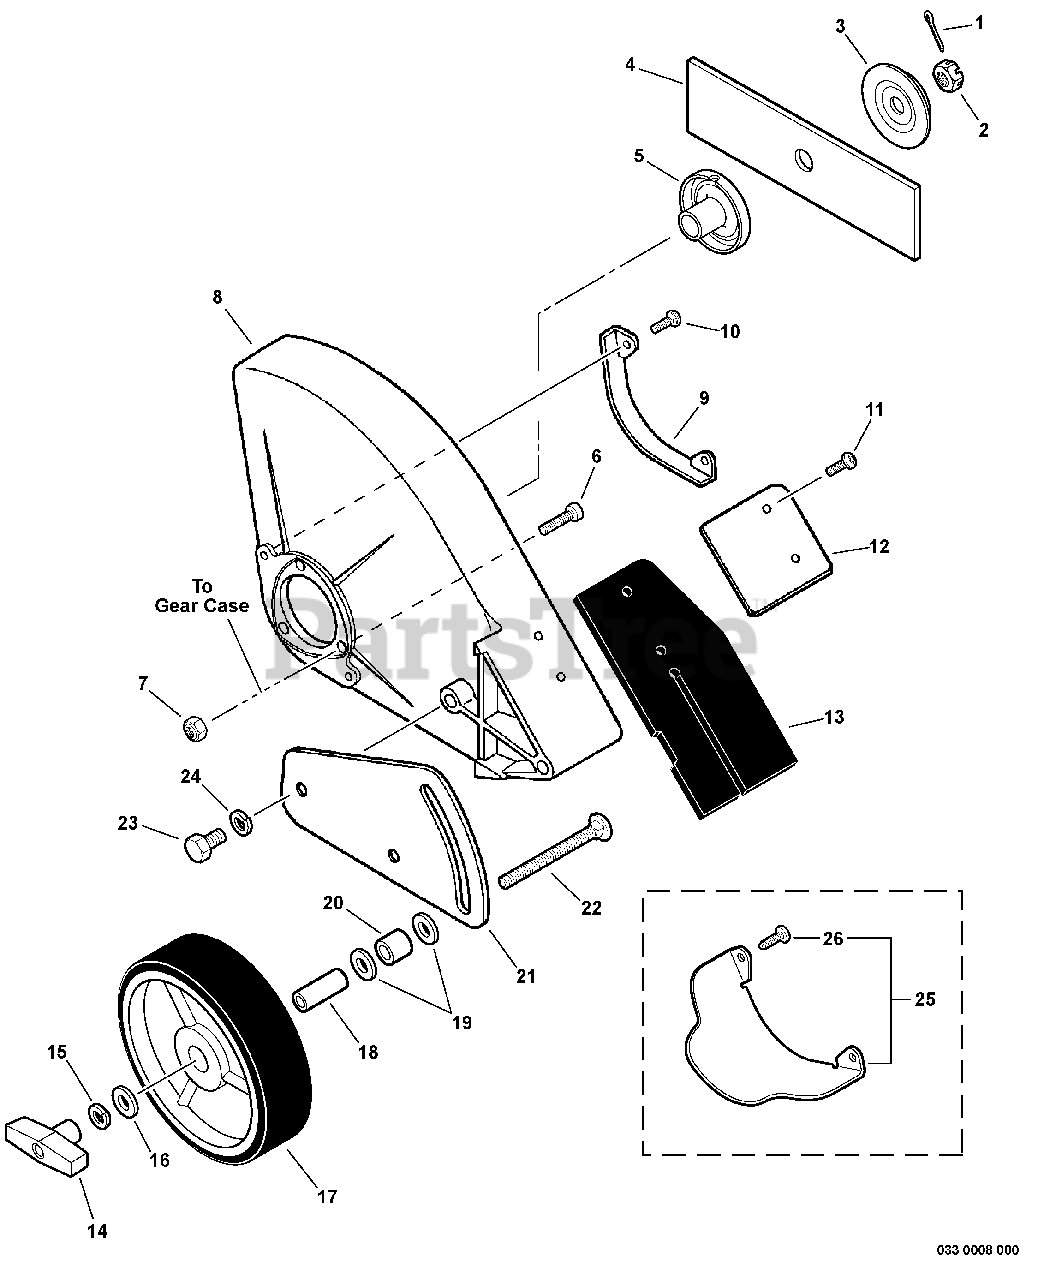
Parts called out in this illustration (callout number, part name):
1	PIN, SPLIT - 2X22
2	LOCKNUT - LEFT HAND
3	ADAPTOR, BLADE - LOWER
4	BLADE, EDGER
5	ADAPTOR, BLADE - UPPER
6	SCREW - 5X20
7	LOCKNUT - 5
8	SHIELD, BLADE
10	SCREW - 4X12
11	SCREW - 4X12
12	PLATE, FLAP
13	FLAP, DEBRIS
14	WINGNUT - 5/16-18
15	LOCKWASHER - 8
16	WASHER - 8
17	WHEEL - 6X1.5
18	COLLAR - 12
20	WASHER - 10
21	BRACKET, WHEEL
22	BOLT - 5/16-18 X 3"
23	BOLT - 8X14
24	LOCKWASHER - 8
25	SHIELD GUARD KIT
26	SCREW - 4X12 -- TAPPING
